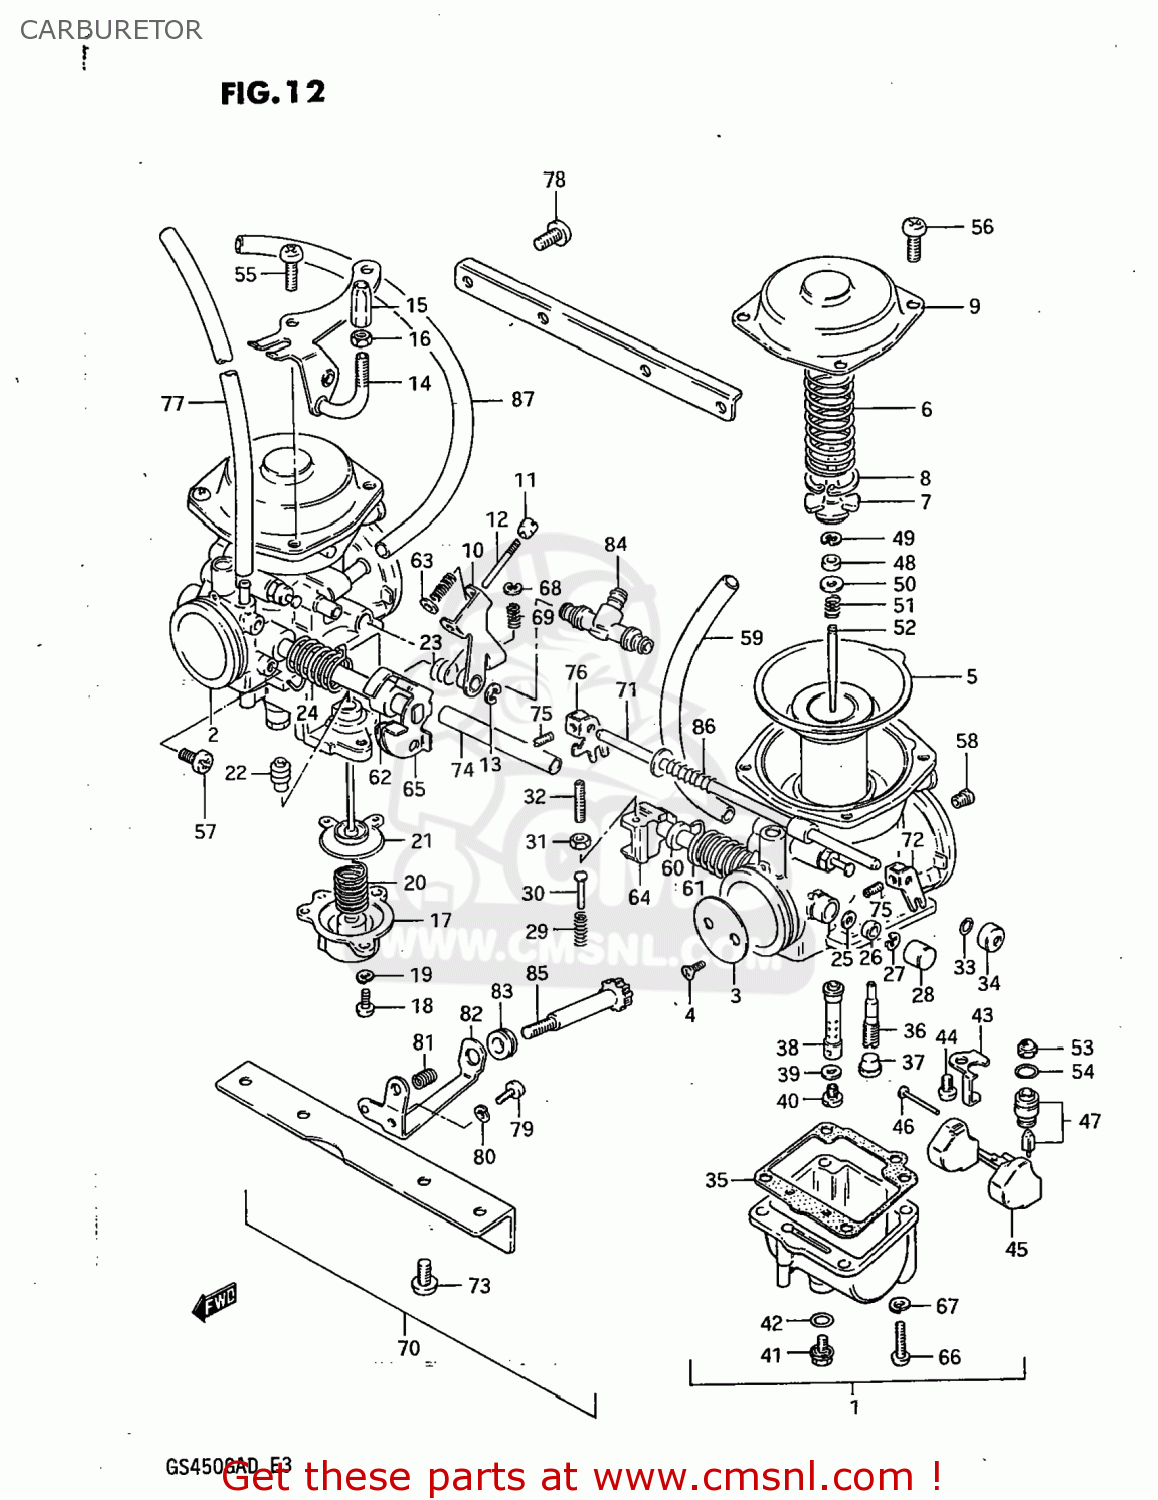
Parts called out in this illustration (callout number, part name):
1	CARBURETOR ASSEMBLY,LEFT (BS
2	CARBURETOR ASSEMBLY
3	VALVE,THROTTLE
4	SCREW
5	DIAPHRAGM ASSEMBLY
6	SPRING
7	HOLDER,GUIDE
8	E RING
9	COVER
10	LEVER,ACCELERTION PUMP
11	O-RING
13	E RING,ACCELETION LEVER
14	BRACKET
15	ADJUSTER
16	NUT
17	COVER ASSEMBLY,DIAPHRAGM
18	SCREW 4X10
19	LOCK WASHER
20	SPRING,ACCELERATOR PUMP
21	DIAPHRAGM ASSY,ACCELERATING
22	BOOT, ACCELE PUMP ROD
23	SPRING
24	SPRING
25	SEAL
26	GASKET,THROTTLE SHAFT (NAS)
27	E RING
28	CAP
29	SPRING,THROTTLE SCREW
30	PIN,THROTTLE LEVER
31	NUT
32	SCREW
33	O RING
34	CAP,STARTER VALVE
35	GASKET,FLOAT CHAMBER
36	JET,PILOT(42.5)
37	PLUG,NEEDLE JET
38	JET,NEEDLE
39	WASHER,NEEDLE NOZZLE
40	JET,MAIN(120)
41	PLUG,DRAIN
42	GASKET (NAS)
43	PLATE,NEEDLE VALVE FITING
44	SCREW 4X6
45	FLOAT
46	PIN,FLOAT
47	VALVE ASSY,NEEDLE
48	RING
49	CLIP
50	WASHER,JET NEEDLE
51	SPRING
52	NEEDLE JET
53	FILTER
54	O-RING,NEEDLE VALVE
55	SCREW
56	SCREW
57	SCREW
58	JET,AIR(135)
59	HOSE
60	SPACER,THROTTLE SHAFT
61	SPRING
62	SPACER,THROTTLE SHAFT
63	GUIDE,HOLDER
64	SHAFT ASSEMBLY
65	SHAFT ASSEMBLY
66	SCREW
67	LOCK WASHER
68	E-RING
69	SPRING,THROTTLE SCREW
70	CARBURETOR ASSEMBLY
71	SHAFT,STARTER
72	LEVER
73	SCREW 6X12
74	HOSE
75	SCREW
76	LEVER,STARTER
77	HOSE
78	SCREW
79	SCREW
80	LOCK WASHER
81	SPRING,THROTTLE ADJUST
82	BRACKET,THROTTLE ADJUST
83	CAP,RUBBER
84	NIPPLE,CARBURETOR
85	SCREW
86	SPRING,STARTER
87	HOSE (5*8*300)
